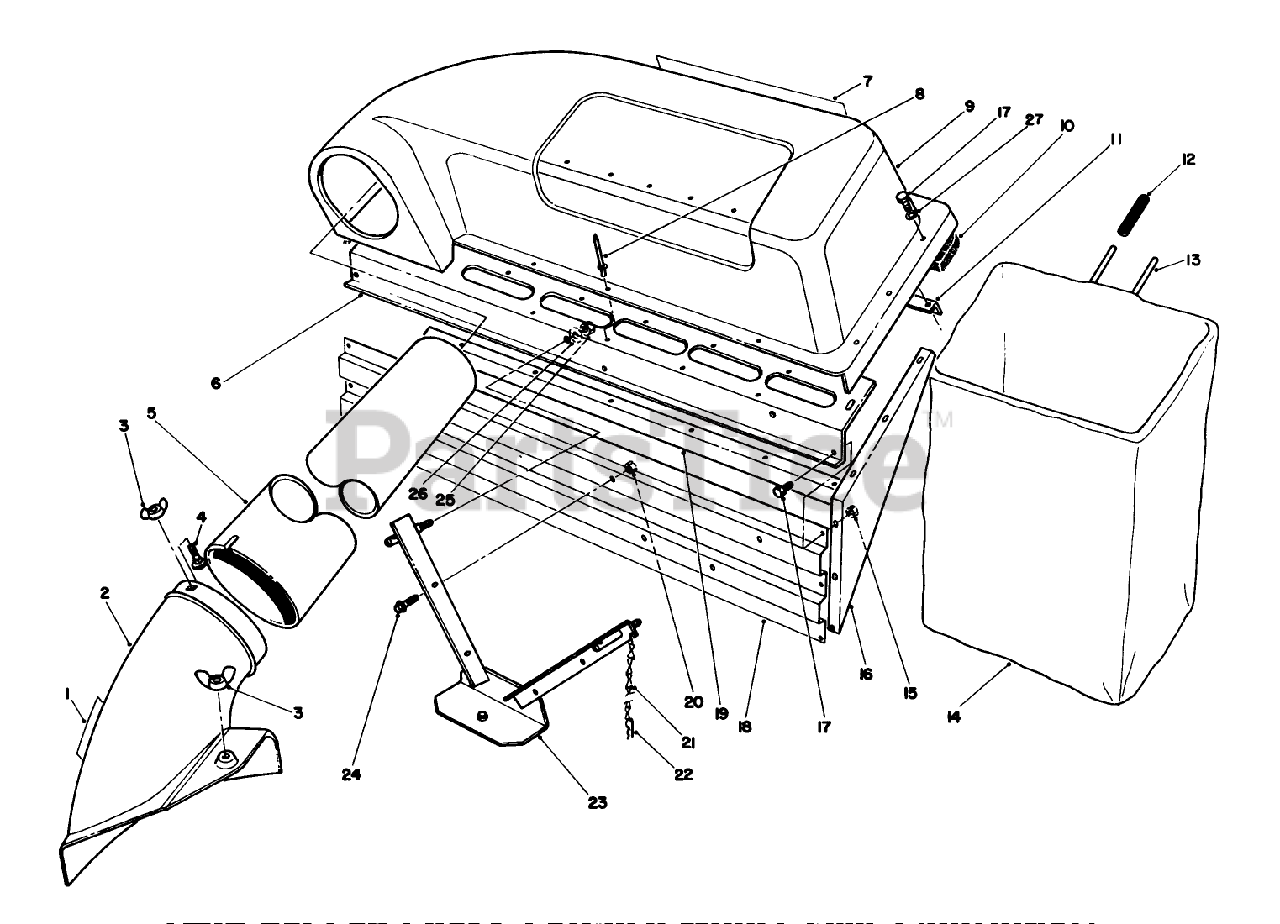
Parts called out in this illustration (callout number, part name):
3	NUT-WING SPECL
4	BOLT-CARR
6	COVER SUPT BAFFLE *B
7	TWIN BAGGER DECAL
8	RIVET-POP
9	COVER
10	FOAM SEAL
11	BAG FRAME BRKT
12	GRIP-HANDLE, BAG
13	BAG FRAME
15	NUT-LOCK, NI
17	SCREW-HH
18	MUFFLER SHIELD *
19	BAG SUPPORT CHANNEL
20	NUT-LOCK, NI
22	PIN-HAIR
24	SCREW-HH
26	WASHER-FLAT
27	WASHER-FLAT
